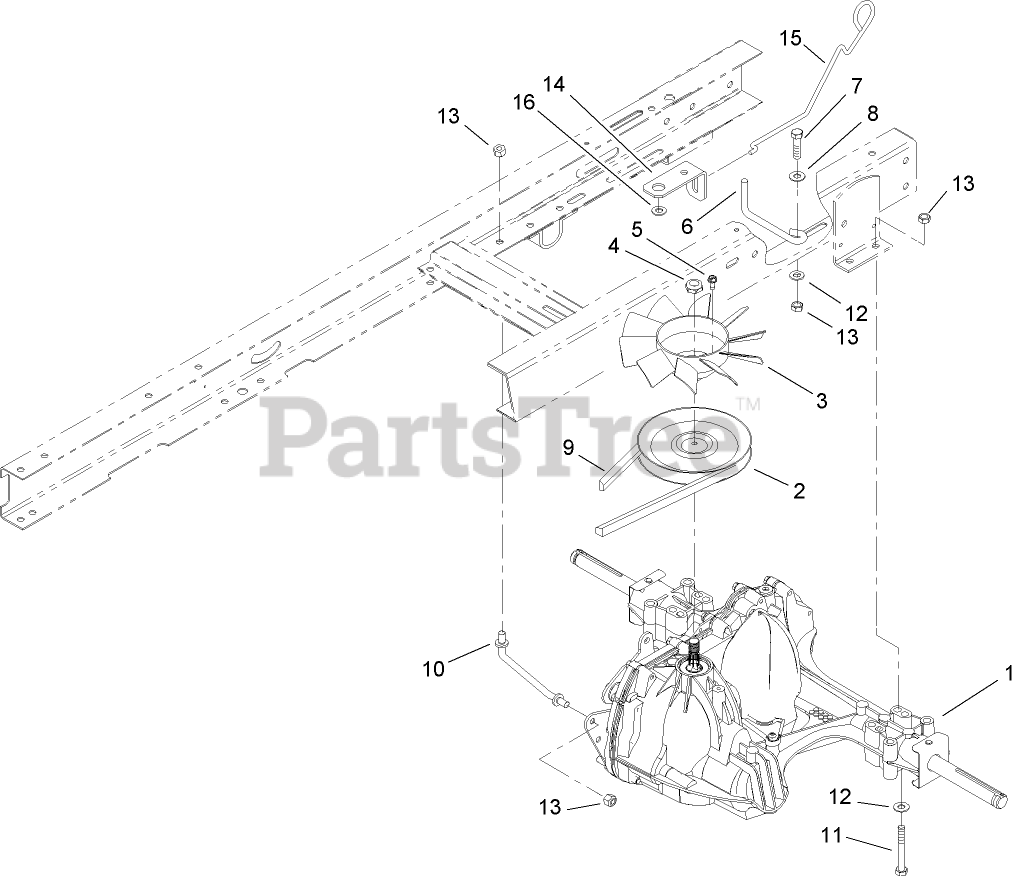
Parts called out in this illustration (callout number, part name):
1	TRANSAXLE ASM
2	PULLEY
4	NUT-LOCK, NI
5	SCREW-HWH
6	GUIDE-BELT
7	SCREW-HH
8	WASHER-PIVOT
9	V-BELT
10	STRAP-TORQUE
11	SCREW-HH
12	WASHER-PLAIN
13	NUT-LOCK, NI
14	BRACKET-BYPASS
15	ROD-BYPASS
16	WASHER-FLAT
